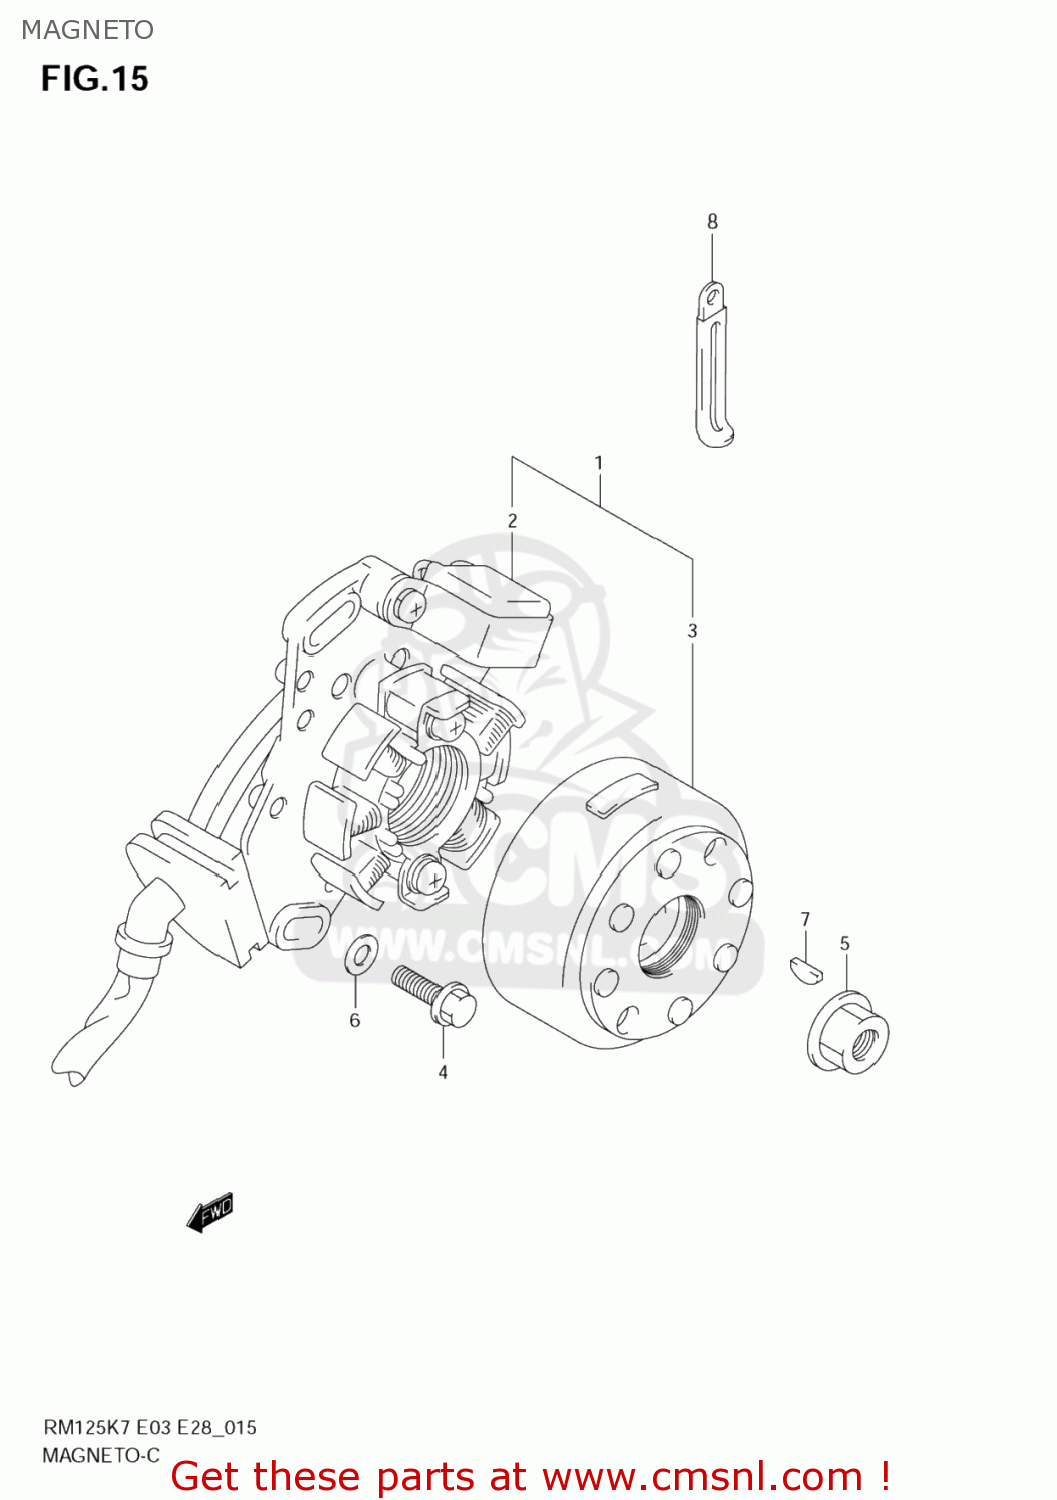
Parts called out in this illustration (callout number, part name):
1	MAGNETO ASSY
2	STARTER ASSY
3	ROTOR ASSY
4	BOLT
5	NUT
6	WASHER
7	KEY
8	CLAMP(L:80)
